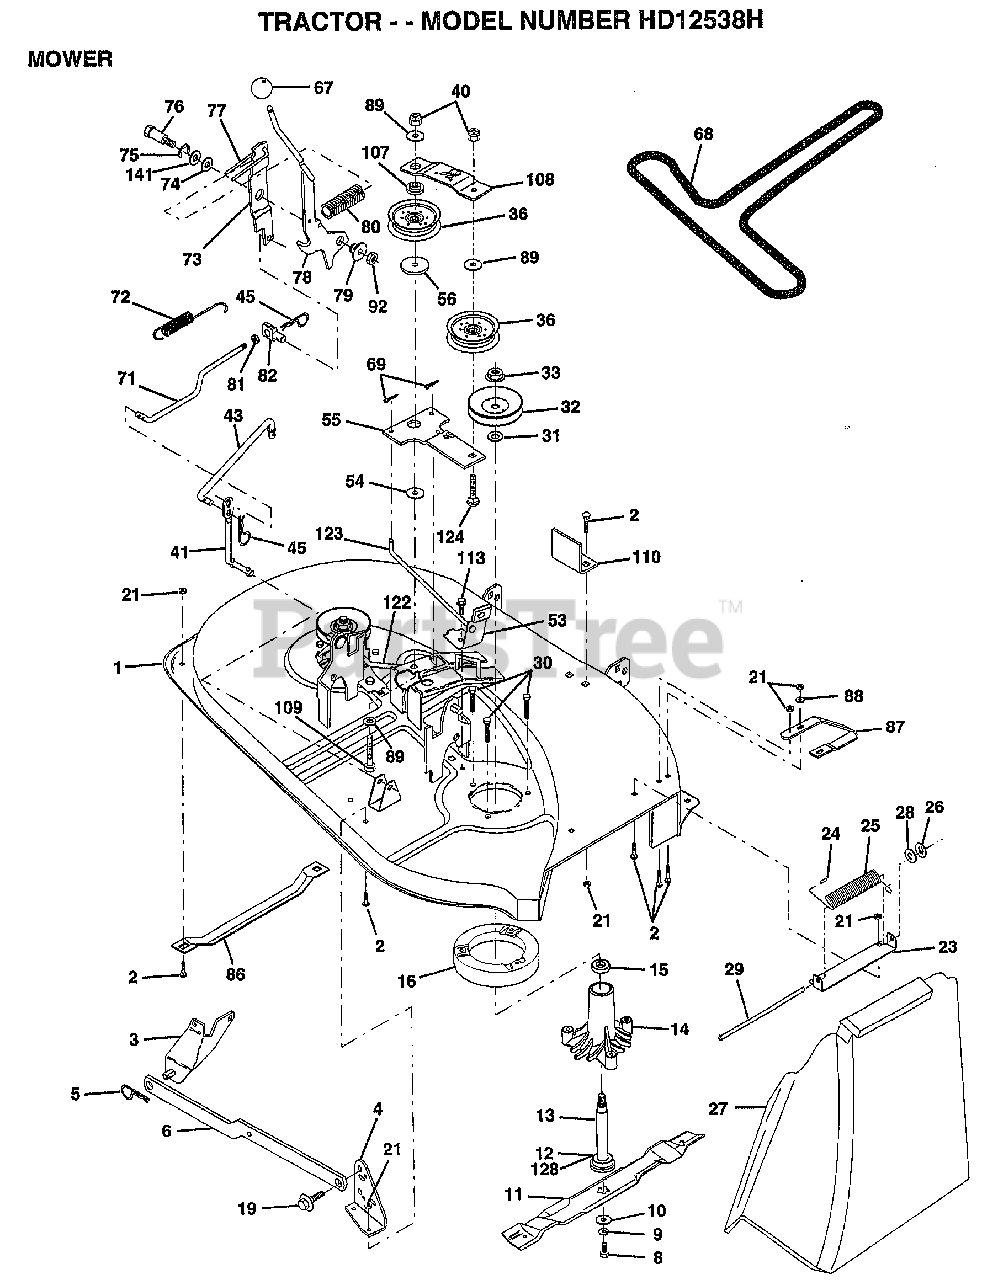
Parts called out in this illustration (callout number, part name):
2	BOLT
3	BRKT ASM SWAY BAR
4	BRKT DECK SW BAR
8	BLADE BOLT
10	WASHER.HARD.BLADE
11	"BLADE.38"" HIPERF"
12	BEARING.BALL
14	HSG ASM MANDREL
15	BEARING
16	STRIPPER RND MWR
19	BOLT SHD 5/16-18
23	BRKT DEFLECTOR
24	CAP-SLEEVE LT
25	SPRING TORSION
26	NUT PUSH M
27	DEFLECTOR-SHLD T
28	WASHER
29	ROD-HINGE T
30	"SCREW-THD ROLL,WA"
31	WASHER
32	PULLEY.MANDREL.38
36	FLAT IDLER PULLEY
41	PIVOT ROD
43	CLUTCH ROD SECOND
45	RETAINER M
53	BRAKE ASM
54	HARDENED WASHER
55	IDLER ARM ASSY
56	SPACER RETAINER
67	KNOB.RD.7/16-14
68	BELT.V.T-PATH
71	ROD CLUTCH 38/42
72	RETURN SPRING
73	CLUTCH ARM SECOND
74	WASHER
75	RING
76	SHOULDER BOLT
77	SPRING KEEPER
78	LEVER.ASM.CLUTCH
79	BUSHING
80	SPRING.CLUTCH.MWR
81	NUT
82	TRUNION ADJ
86	RUNNER-LH M
87	RUNNER RH
88	WASHER M
89	WASHER GT
92	NUT
107	RETAINER SPACER
108	IDLER ARM STIFF
109	BOLT
110	UPSTOP DECK FT 38
113	SCREW
122	BRAKE ROD LH
123	BRAKE ROD RH
124	BOLT
128	WASHER.FELT.
141	WASHER .T
